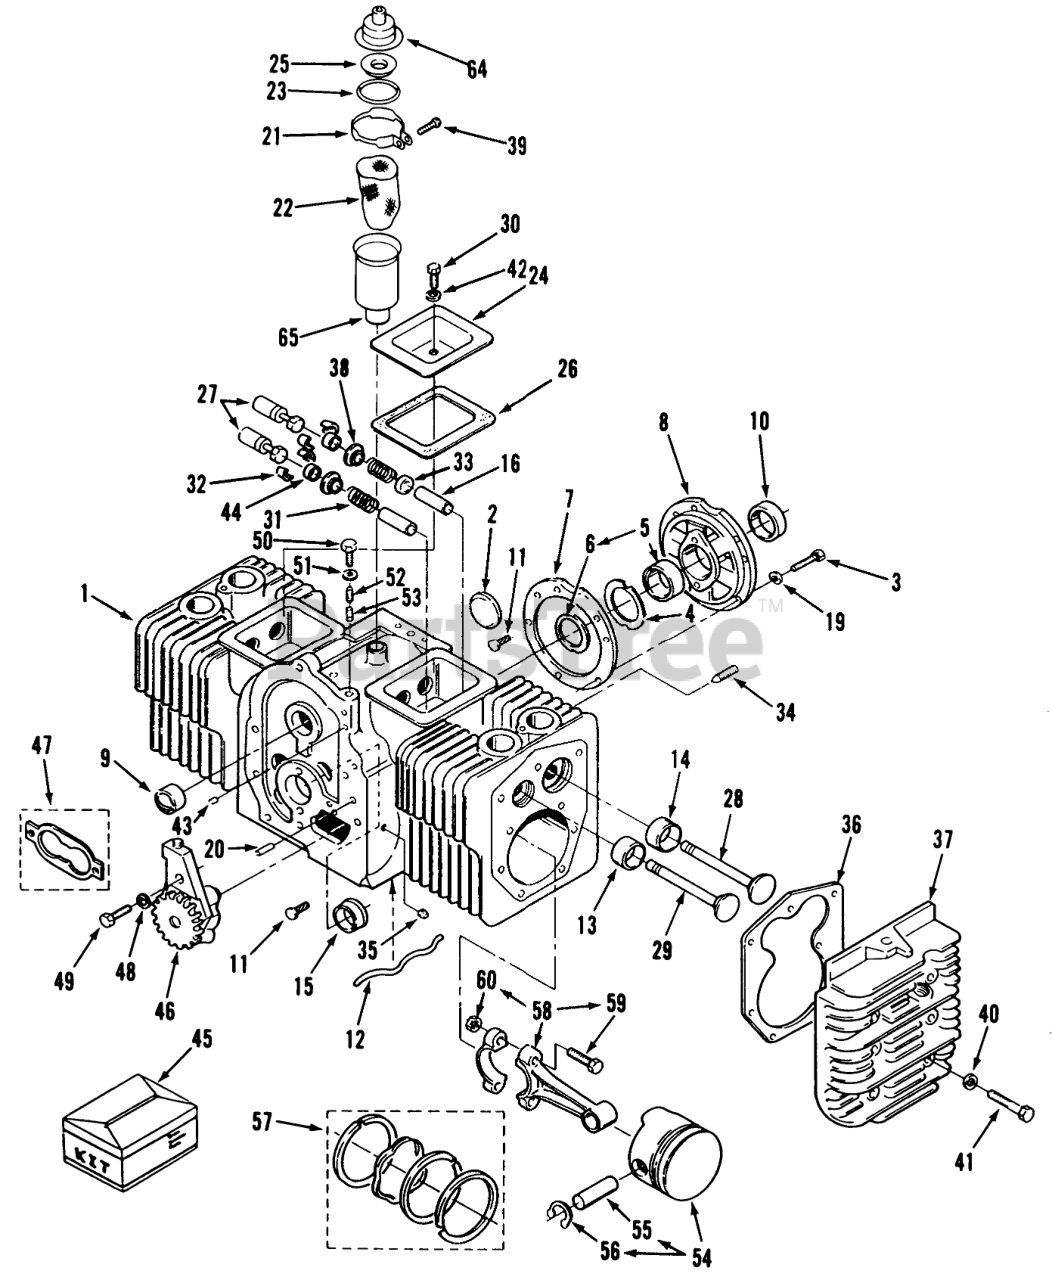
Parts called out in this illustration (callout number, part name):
1	SHORT-BLOCK
3	Bolt 3/8-16 x 1-1/4
5	Rear Crankshaft Bearing-STD
6	Thrust Washer
7	GASKET
8	Bearing Plate
9	Camshaft Brg
11	PIN-DRIVE
12	OIL TUBE
13	STD INSERT
14	STD INSERT
15	Standard
16	Guide-ExhaustValve
19	Washer
20	Pin
21	Clamp
22	FILTER
23	SEAL - O-RING
24	VALVE-COVER L.H.
25	SCREEN-BREATHER TUBE
26	Gasket
27	Tappet
28	Intake Valve
29	Intake Valve
30	HHCS 1/4-20 X 1 3/4
31	Spring
32	VALVE SPRING LOCK
34	Screw
35	Plug
36	Gasket
37	Right Side
38	Washer
39	SCREW-TAPPING, ROUND HEAD
40	WASHER
41	Bolt
42	Washer
43	PLUG-CORE HOLE
44	VALVE CAP
45	Engine Gasket Kit
47	GASKET KIT
48	WASHER-FLAT
50	SCREW-HH
51	WASHER
52	Spring
53	Piunger
54	Standard
55	Pin-Piston
56	Retaining Ring
57	RING SET
58	CONNECTING ROD W/NUT
59	Rod Bolt
60	Nut
64	BREATHER-CAP AND VALVE
65	TUBE-BREATHER
